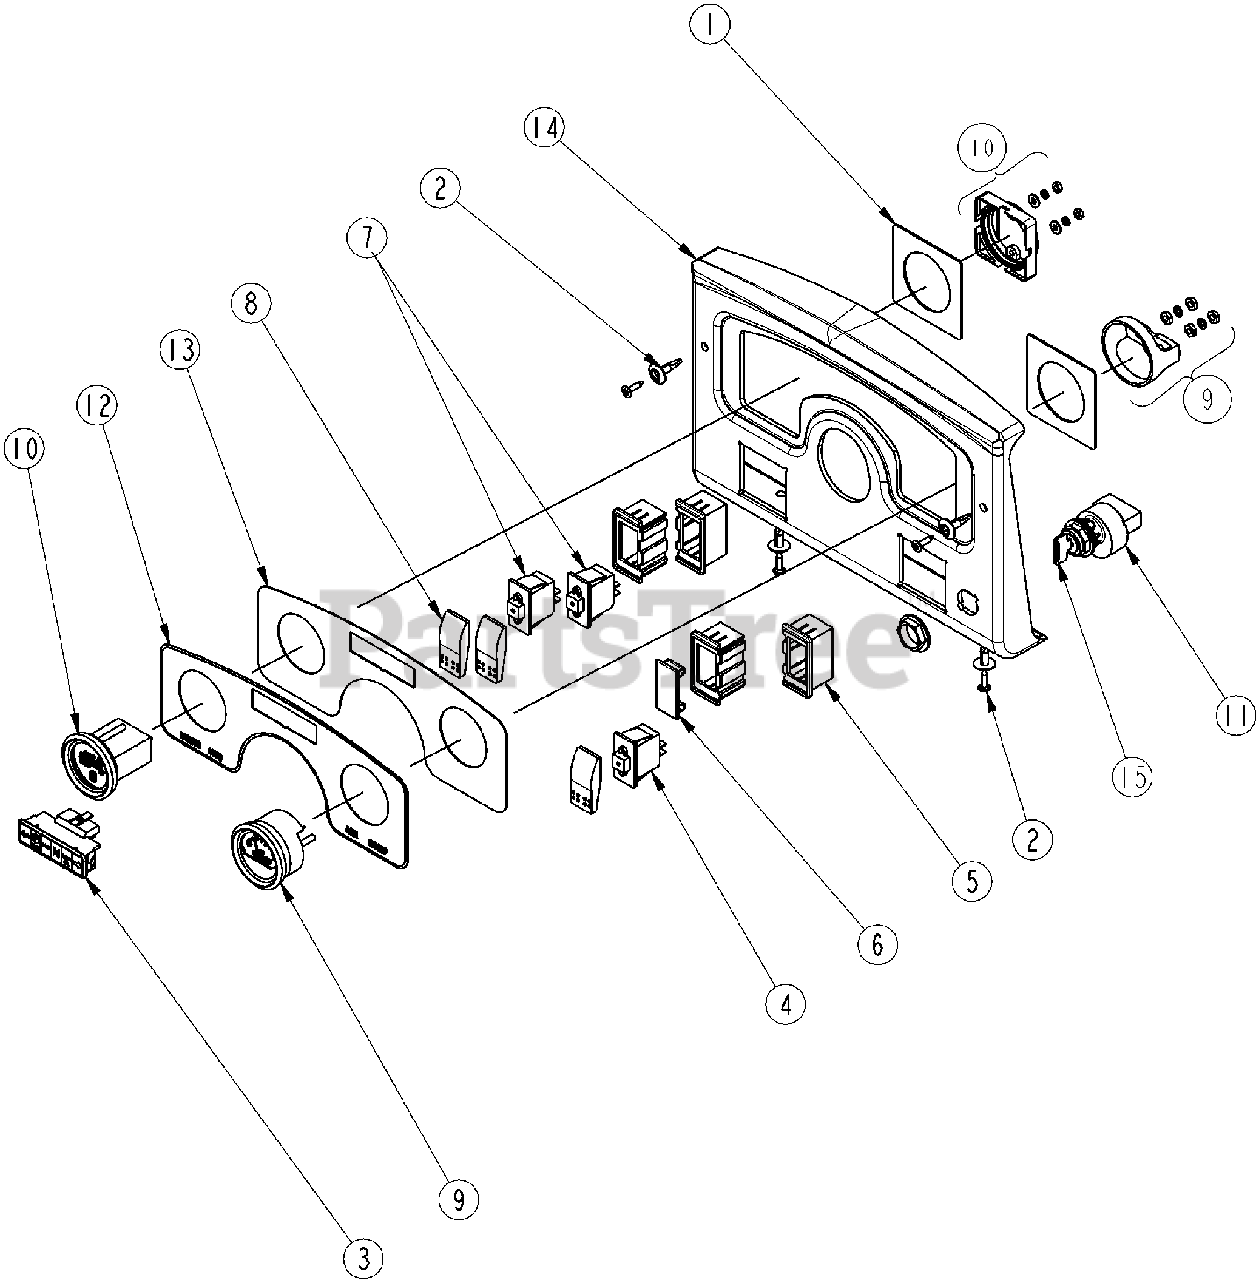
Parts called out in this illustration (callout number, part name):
1	DASH BACKER PLATE
2	RIVET, 1/4
3	INDICATOR LIGHT STRIP 8-PIN Replacement Bulb 833-418c
4	DUMP SWITCH WAYTEK 44304
5	SWITCH MOUNT END
6	PANEL PLUG
7	SWITCH ROCKER SPST
8	SWITCH ACTUATOR
9	GAUGE, VOLT METER
10	GAUGE, HOUR METER
11	IGNITION SWITCH W/2 KEYS (6-PIN)
12	DECAL INSTR. PANEL TRUCK 4X4
13	INSTRUMENT PANEL
14	DASH TRUCK
15	KEY W/SHIELD (RP FOR 833-336C)
